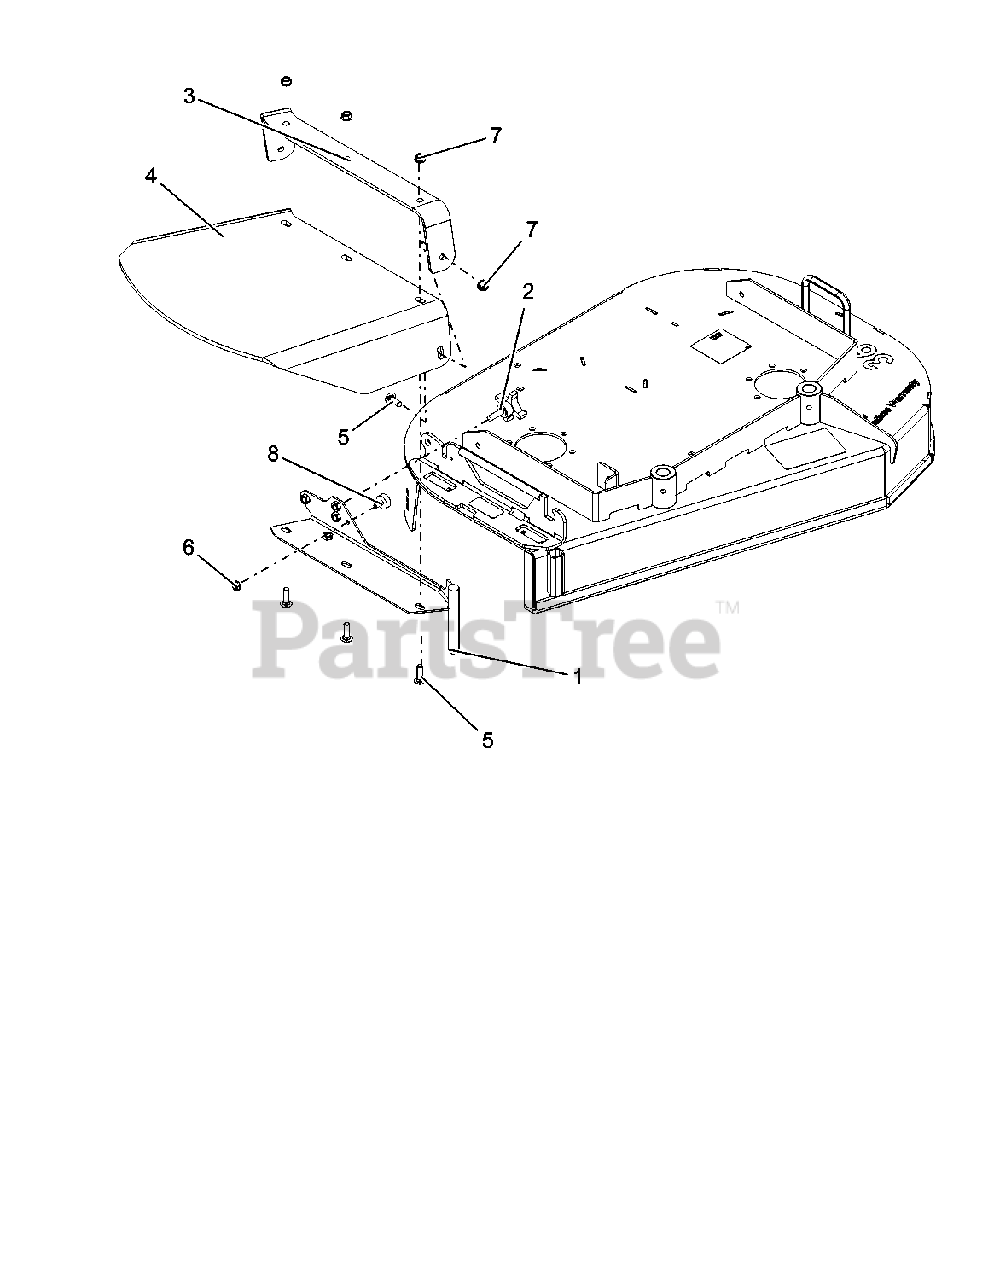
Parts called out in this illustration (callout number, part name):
1	WLDT. DISCHARGE-RED
2	KNOB, 3/8 X 1.25 - 4 PRONG
3	STRAP, WALK RUBBER DISCHARGE-RED
4	SHIELD, WALK RUBBER DISCHARGE
5	BLT-RDHDSQNK .38-16X1.25 G5 YWZC
6	@NUT-SPNLK-FLG .312-18 YWZC
7	@NUT-SPNLK-FLG .375-16 YWZC
8	BUMPER, RUBBER
